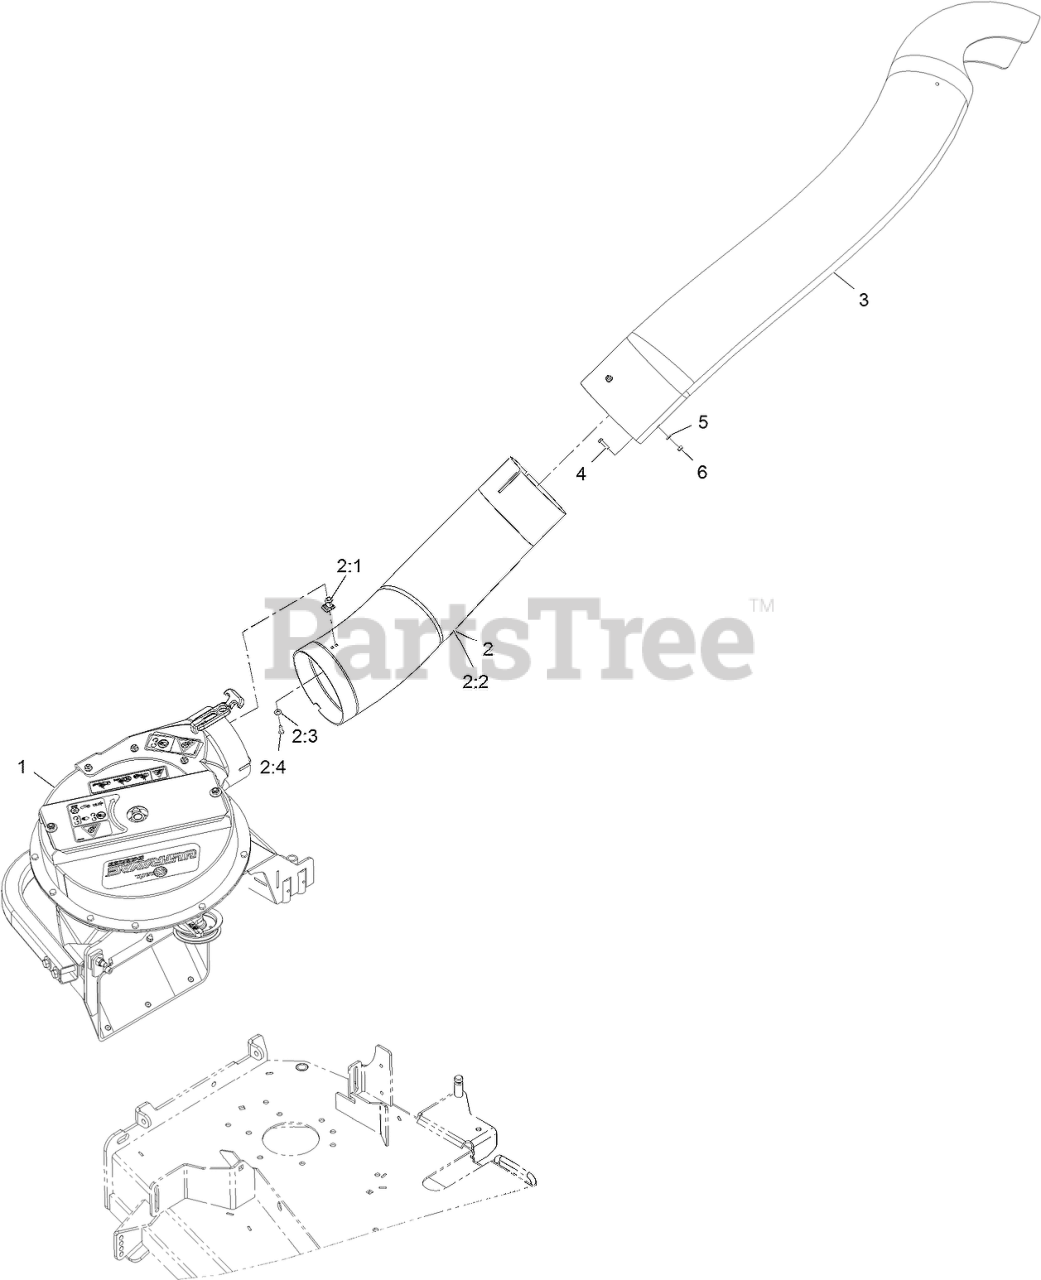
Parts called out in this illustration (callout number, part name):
1	ASM- BLOWER
2	LOWER TUBE ASM
2:1	Tube, Lower Short
2:2	LATCH-KEEPER
2:3	SCREW-PPH
2:4	WASHER-FLAT
3	TUBE-UPPER
4	SCREW-HWH
5	WASHER-FLAT
6	NUT-LOCK, NI
